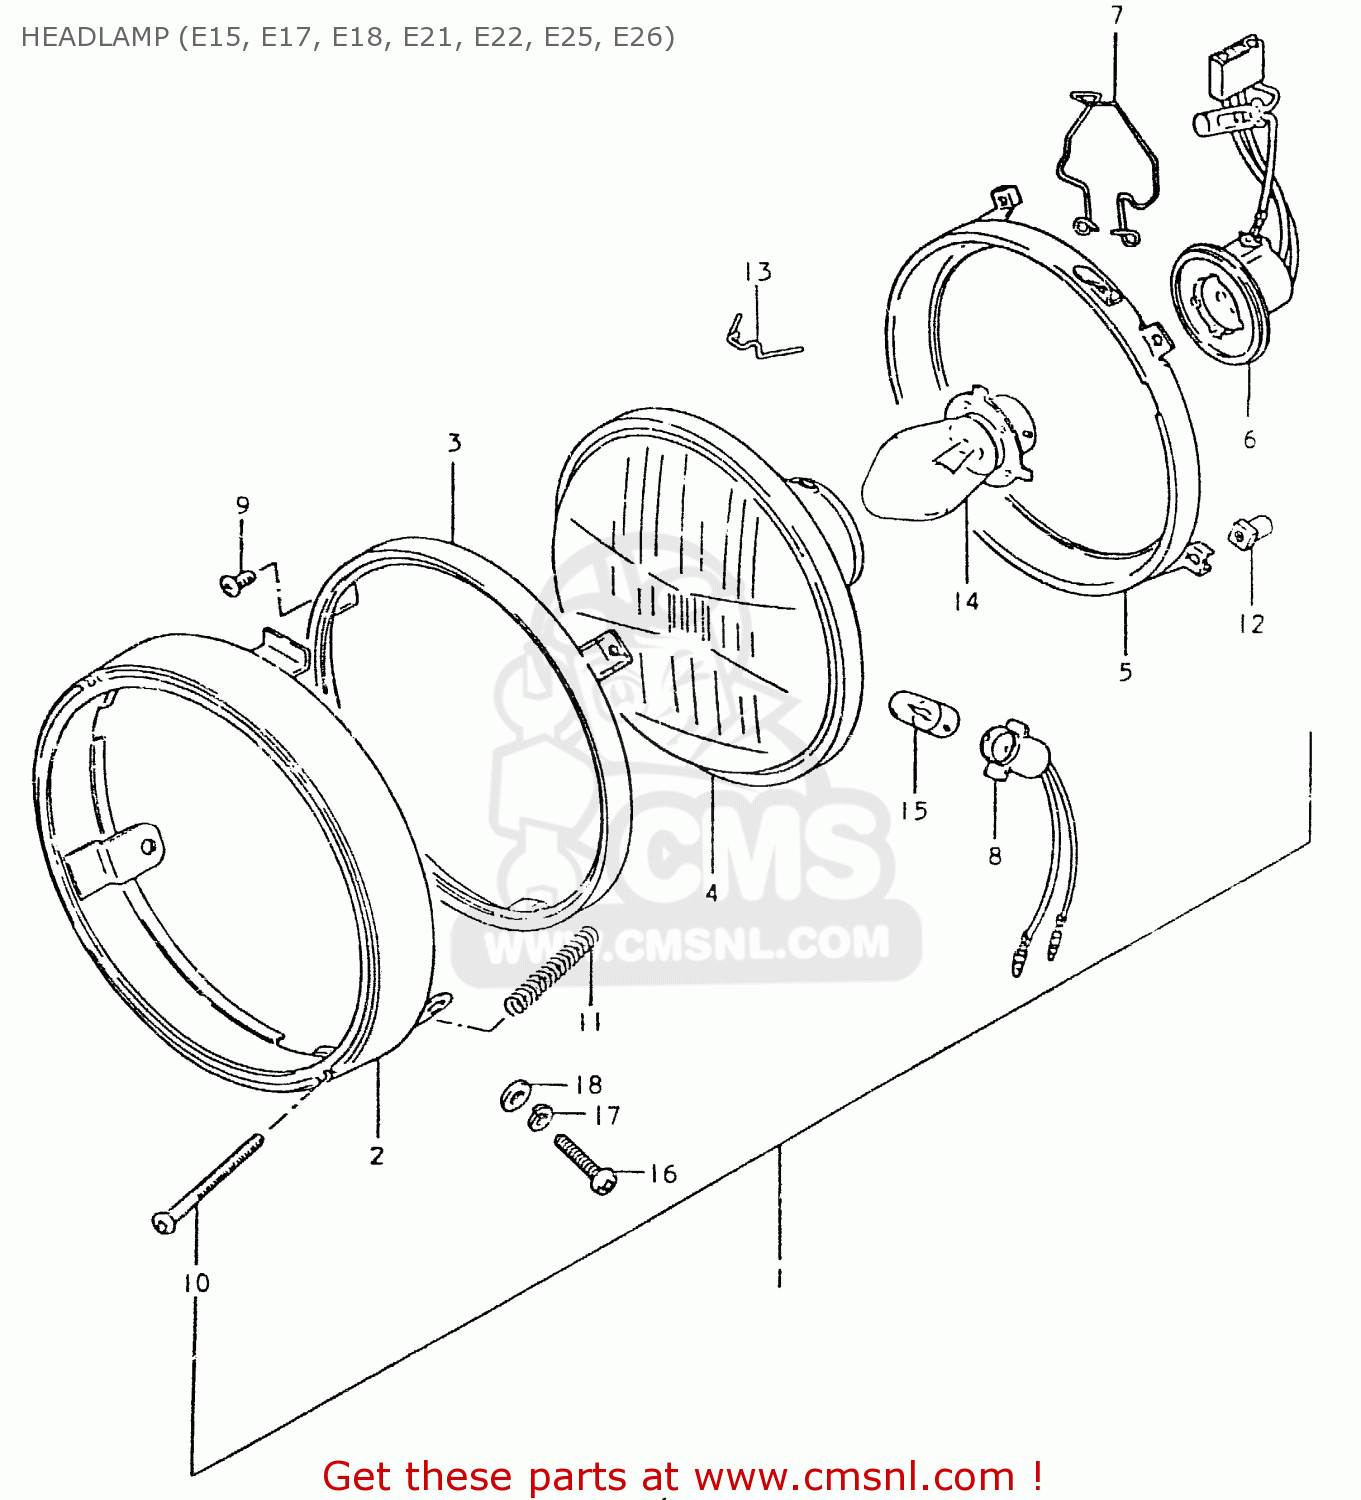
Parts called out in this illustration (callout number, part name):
1	HEADLAMP ASSY
2	RIM
3	RETAINER,HEADLAMP
4	UNIT
5	RING, MOUNTING
6	SOCKET
7	CLAMP,HEADLAMP
8	SOCKET
9	SCREW
10	SCREW,HEADLAMP ADJUST
11	SPRING,ADJUSTING
12	NUT,HEADLAMP ADJUSTER
13	SPRING,HEADLAMP UNIT
14	BULB (6V,25/25W)
15	BULB(6V4W,STANLEY,A1364J)
16	SCREW
17	LOCK WASHER
18	WASHER
